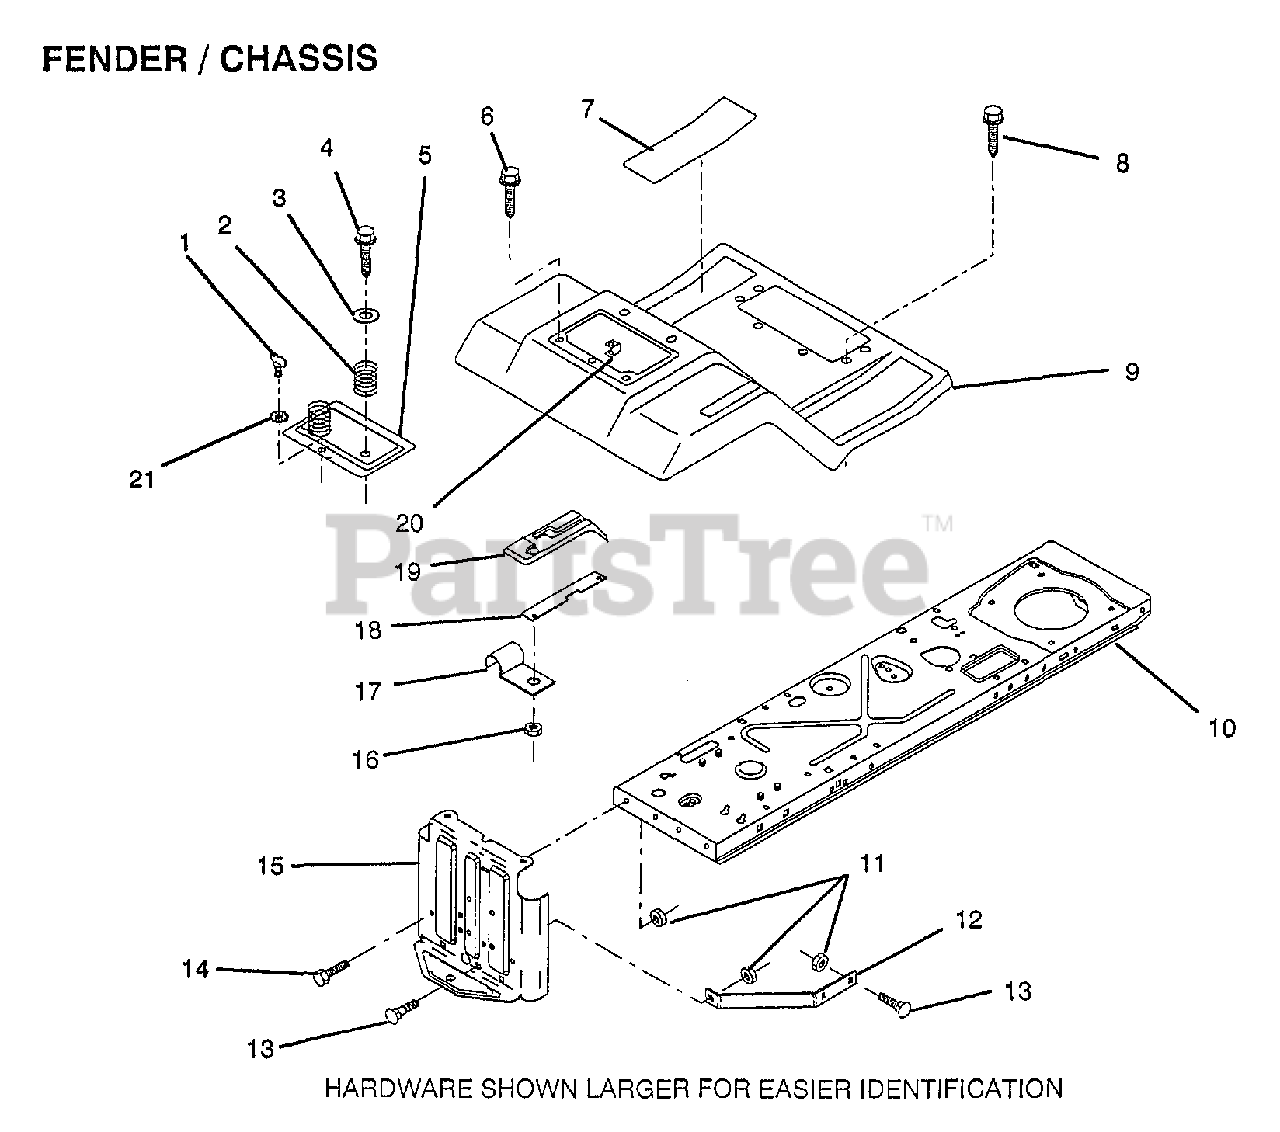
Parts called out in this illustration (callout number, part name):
1	STUD.1/4.TURN
2	SPRING COMPRESSIO
3	WASHER
4	SCREW
6	SCREW LT
7	PAD FOOTREST
8	SCREW
9	FENDER/FOOTREST
10	FRAME ASS'Y
12	"BRACE,DRAWBAR "
13	BOLT
14	BOLT
15	DRAWBAR
16	NUT
17	"CLIP,INSULATOR"
19	"CONSOLE,SHIFT CON"
20	RECEPTACLE LT
21	RETAINER LT
